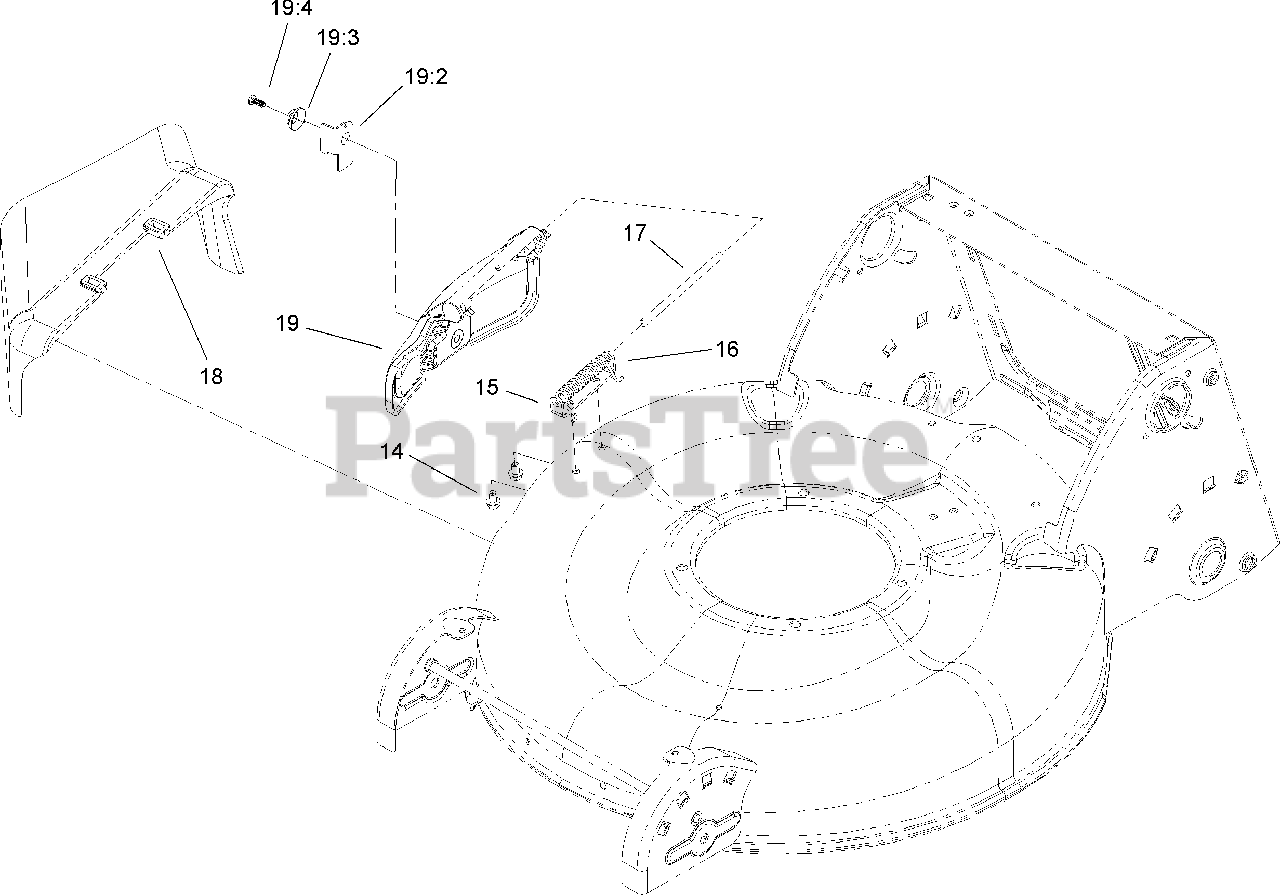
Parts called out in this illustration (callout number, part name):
14	SCREW-HWH
15	SPRING-TORSION
16	BRACKET-COVER
17	ROD-COVER
18	CHUTE-DISCHARGE, SIDE
19	DISCHARGE DOOR ASM
19:2	LATCH-DOOR
19:3	CAP-DOOR
19:4	SCREW-PLASTITE
